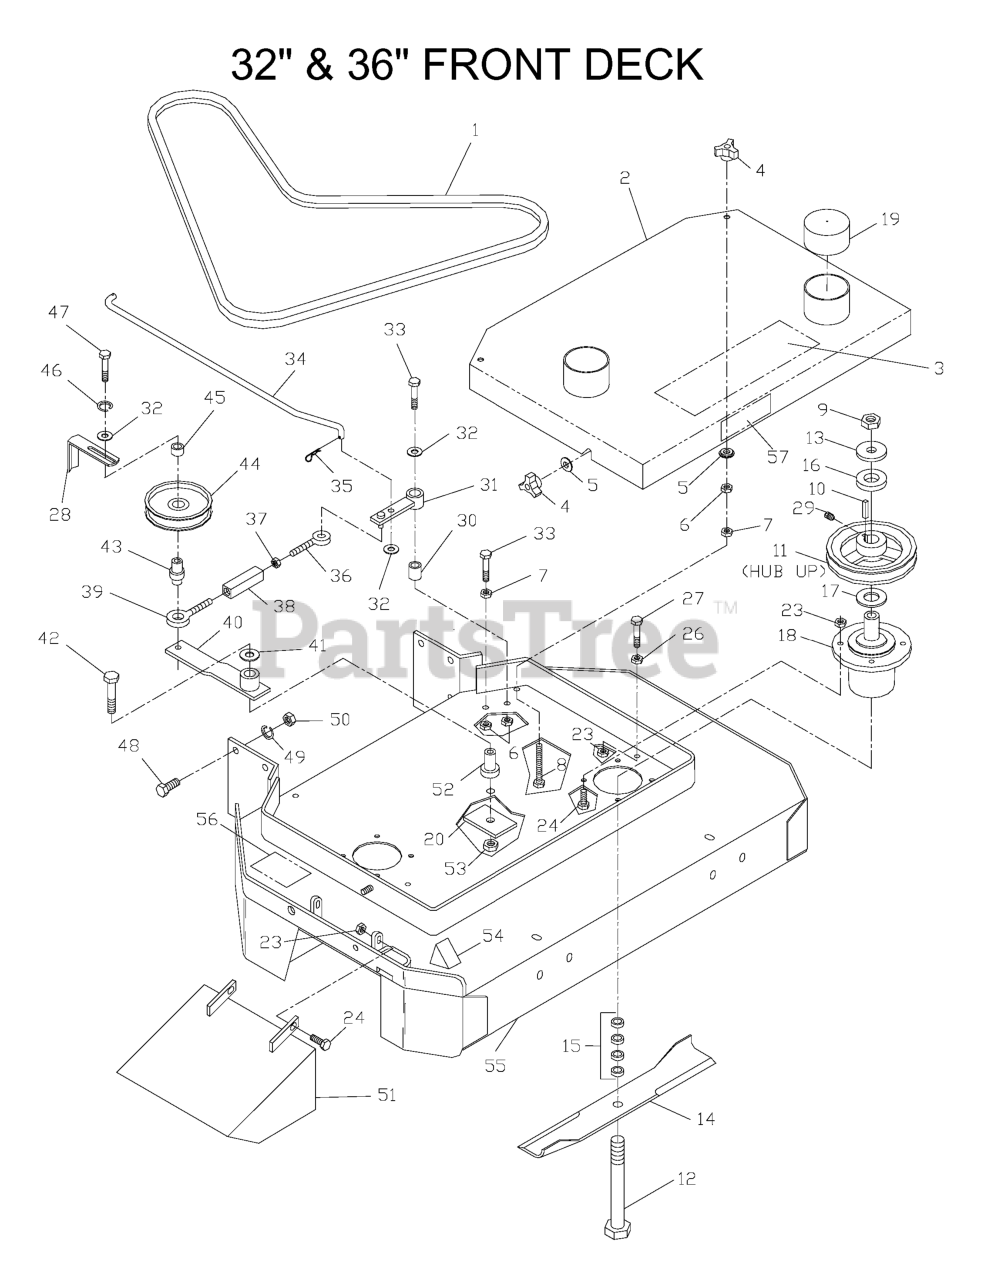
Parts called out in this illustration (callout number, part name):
1	BELT, DECK, 36"
2	BELT SHIELD ORANGE 36"
3	DECAL, HUSQVARNA 17.5"
4	KNOB, THREE PRONG
5	WASHER, 3/8 SEALING
6	NUT 3/8C CENTERBLOCK
7	NUT 3/8C WHIZ
8	TAPBOLT 3/8C X 4 1/2
9	NUT 5/8F HEX
10	KEY 1/4 SQ X 1 1/8
11	PULLEY W/SETSCREWS
12	HCS 5/8F X 8 1/2
13	WASHER, SUPPORT
14	BLADE OEM 18"
15	BLADE SPACERS
17	MACHINERY BUSHING 10 GA.
18	HOUSING ASSEMBLY
23	NUT 5/16C CENTERLOCK
24	HCS 5/16C X 1
26	NUT 5/16C WHIZ
27	HCS 5/16 X 3
29	SET SCREW 5/16 NYLOC
30	BUSHING, SLEEVE
31	ENGAGEMENT ARM
32	WASHER 3/8 FLAT
33	HCS 3/8C X 2 1/4
34	BLADE ROD 36"
35	HAIRPIN #2
36	EYEBOLT, RH
37	NUT 5/16C HEX
38	TURNBUCKLE
39	EYEBOLT, LH
40	ARM WELDMENT
41	WASHER 1/2 FLAT
42	HCS 1/2C X 2 3/4
43	EYEBOLT PIVOT
44	IDLER PULLEY
46	SLW 3/8 STD
47	HCS 3/8C X 2 1/2
48	HCS 7/16C X 1 1/2
49	WASHER 7/16 LOCK
50	NUT 7/16C HEX
51	DEFLECTOR CHUTE
52	IDLER SPINDLE
53	NUT 1/2-13 HEX NYLOC ZD
54	DECAL, CPSC
55	DECK W/DECALS 36"
56	DECAL, DANGER
57	DECAL, NASCAR
539100340	BLADE OEM 16 1/4"
539102148	BELT, DECK 32"
539104620	DECK W/DECALS 32"
539104650	BELT SHIELD 32", ORANGE
